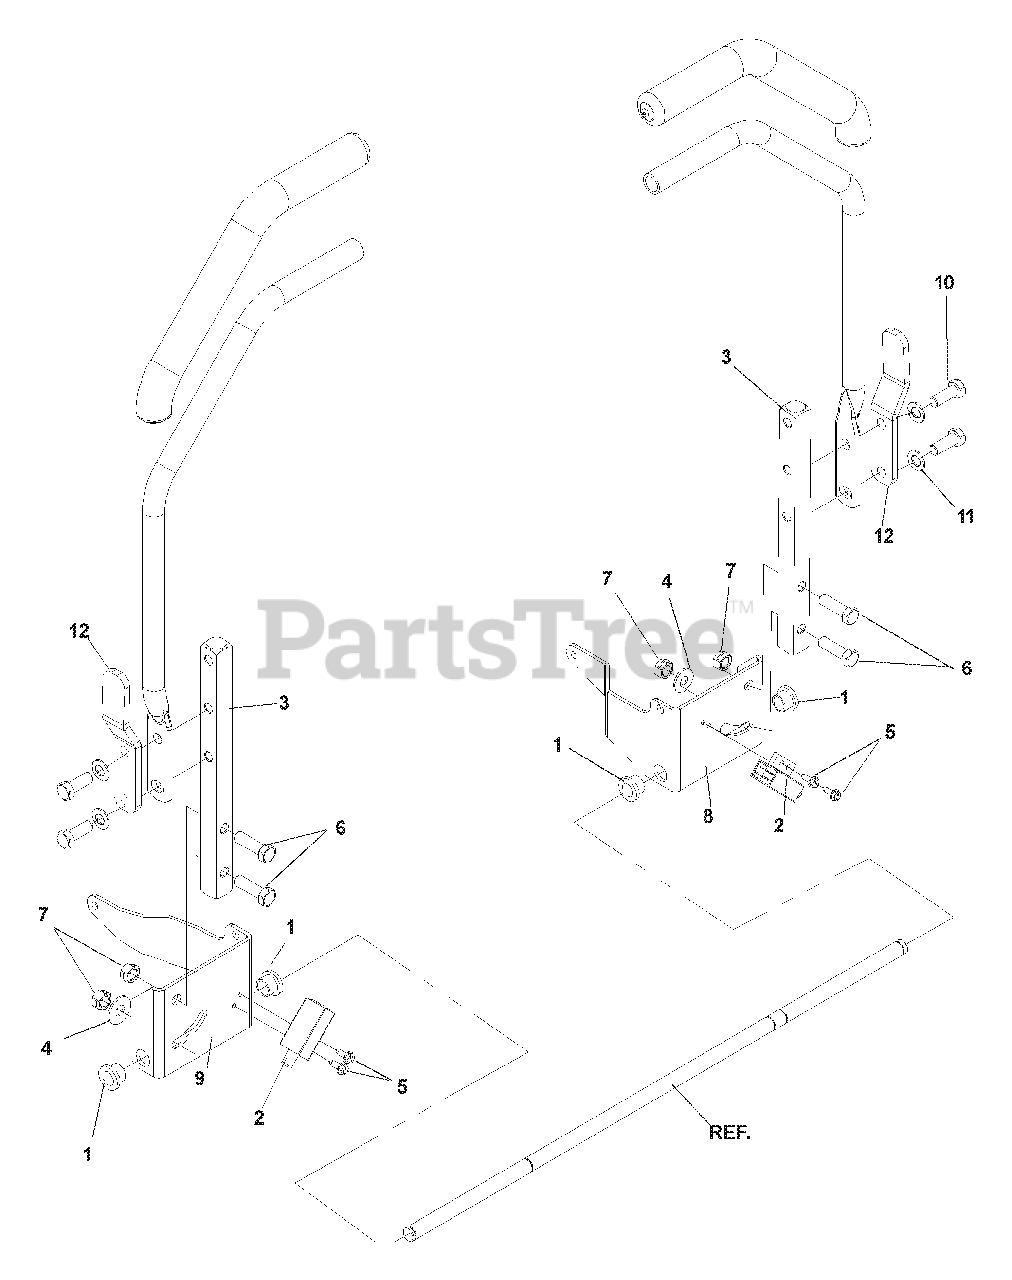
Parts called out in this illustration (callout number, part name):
1	BUSHING, NYLON FLANGED
2	SWITCH N.C.
3	CONTROL ARM
4	WASHER, 3/8 FLAT
5	SCREW 10-24 X 1/2, SELF TAPPING
6	TAPBOLT 3/8C X 1 1/2
7	NUT 3/8C, CENTER LOCK
8	CONTROL BRACKET, LEFT
9	CONTROL BRACKET, RIGHT
10	HCS 3/8C X 1
11	WASHER, 3/8, SPRING
